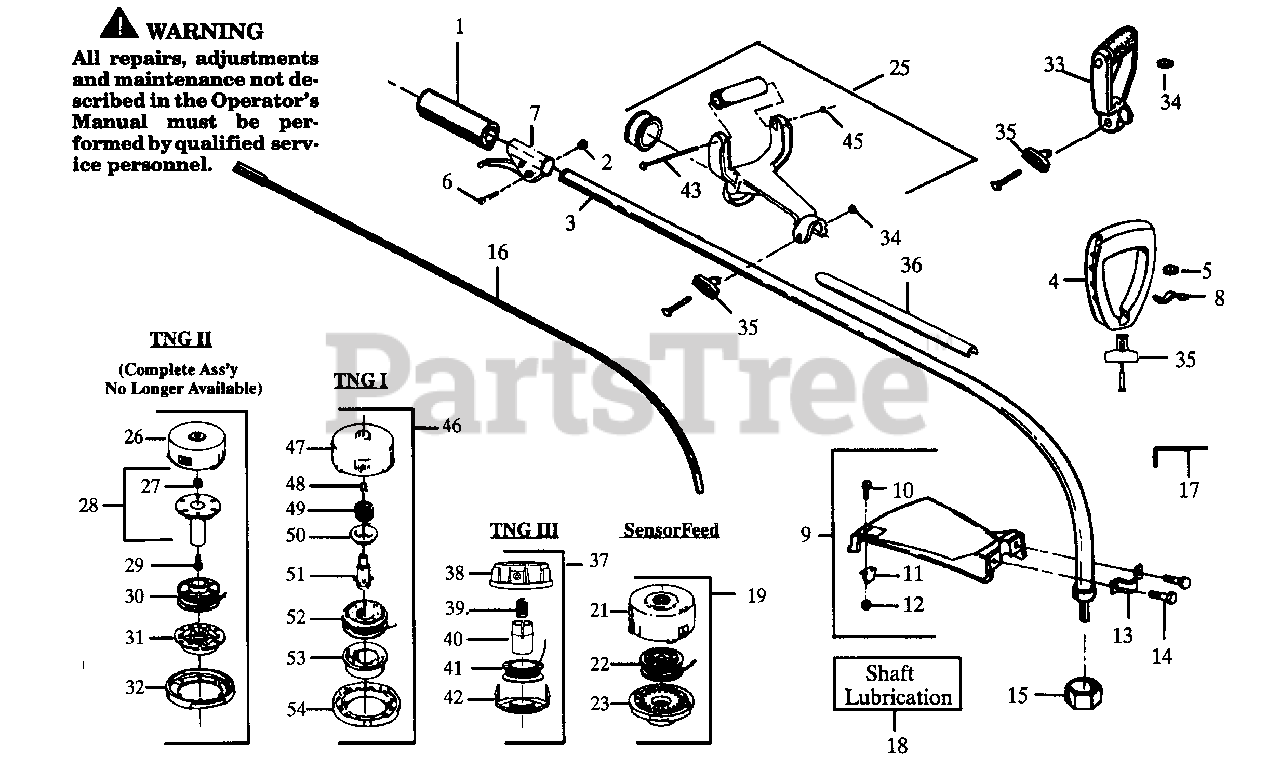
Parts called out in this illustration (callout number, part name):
3	Drive Shaft Housing, Model 111
3	Drive Shaft Housing, Model 114
7	Throttle Housing Ass'y.
9	Shield Kit Ass'y.
11	Line Limiter
12	Locknut
13	Shield Bracket
15	Dust Cup
16	Drive Shaft, Model 111
16	Drive Shaft, Model 114
17	Hex Wrench (5/32)
18	Shaft Lubrication
19	Cutting Head Ass'y.
21	Hub Ass'y.
22	Spool w/Line
25	Anti-Vibe Handle
26	Hub Ass'y.
28	Locking Plate Kit
30	Spool w/Line
32	Release Button
35	"T" Handle Ass'y.
36	Shaft Warning Decal, Type 1-2
36	Shaft Warning Decal, Type 3
37	Cutting Head Ass'y.
38	Hub Ass'y.
40	Release Button
41	Spool w/Line
46	Cutting Head Ass'y.
47	Hub
48	Line Saver
50	Spring Adapter
51	Drive Gear
52	Spool w/Line
53	Release Button
